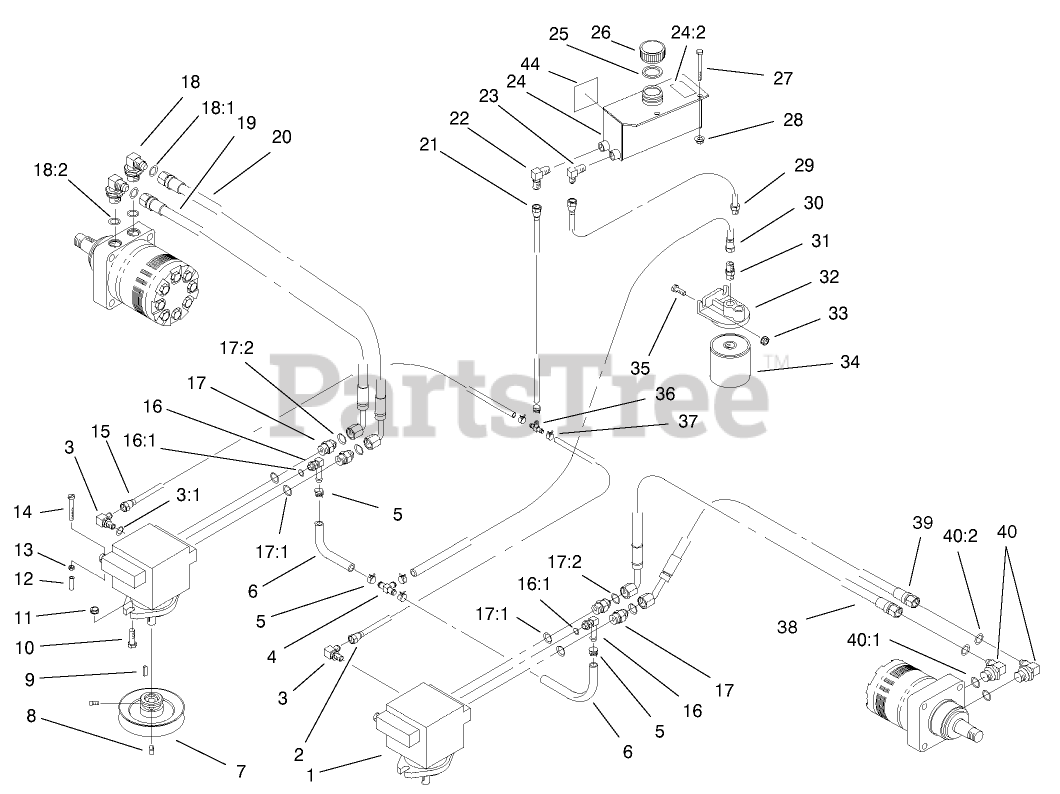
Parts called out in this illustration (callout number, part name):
2	HOSE ASM
3	FITTING-90 DEG
3:1	O-RING
4	FITTING-TEE, HOSE
5	CLAMP-HOSE
7	PULLEY
8	SCREW-SET
10	SCREW-HH
11	NUT-HHF, WHIZ
12	GRIP-VALVE, DUMP
13	NUT-LOCK, NI
15	HOSE ASM
16	FITTING
16:1	O-RING
17	FITTING-STRAIGHT
17:1	O-RING
17:2	O-Ring
18	FITTING-HYD, 90 DEG
18:1	O-Ring
18:2	O-RING
19	HOSE-FRONT
20	HOSE-REAR, RH
22	FITTING-ELBOW
23	FITTING-ELBOW
24	HYDRAULIC TANK ASM
24:2	DECAL-TANK, HYD
25	GASKET-CAP, TANK
27	SCREW-HH
28	NUT-HF
31	FITTING-STRAIGHT
32	HEAD-FILTER
33	NUT-HF
34	FILTER-OIL, HYD
34	FILTER-OIL, HYD (WINTER)
35	SCREW-HH
36	FITTING-TEE, HOSE
37	CLAMP-HOSE
40:1	O-RING
40:2	O-Ring
44	DECAL-MOBIL 1
